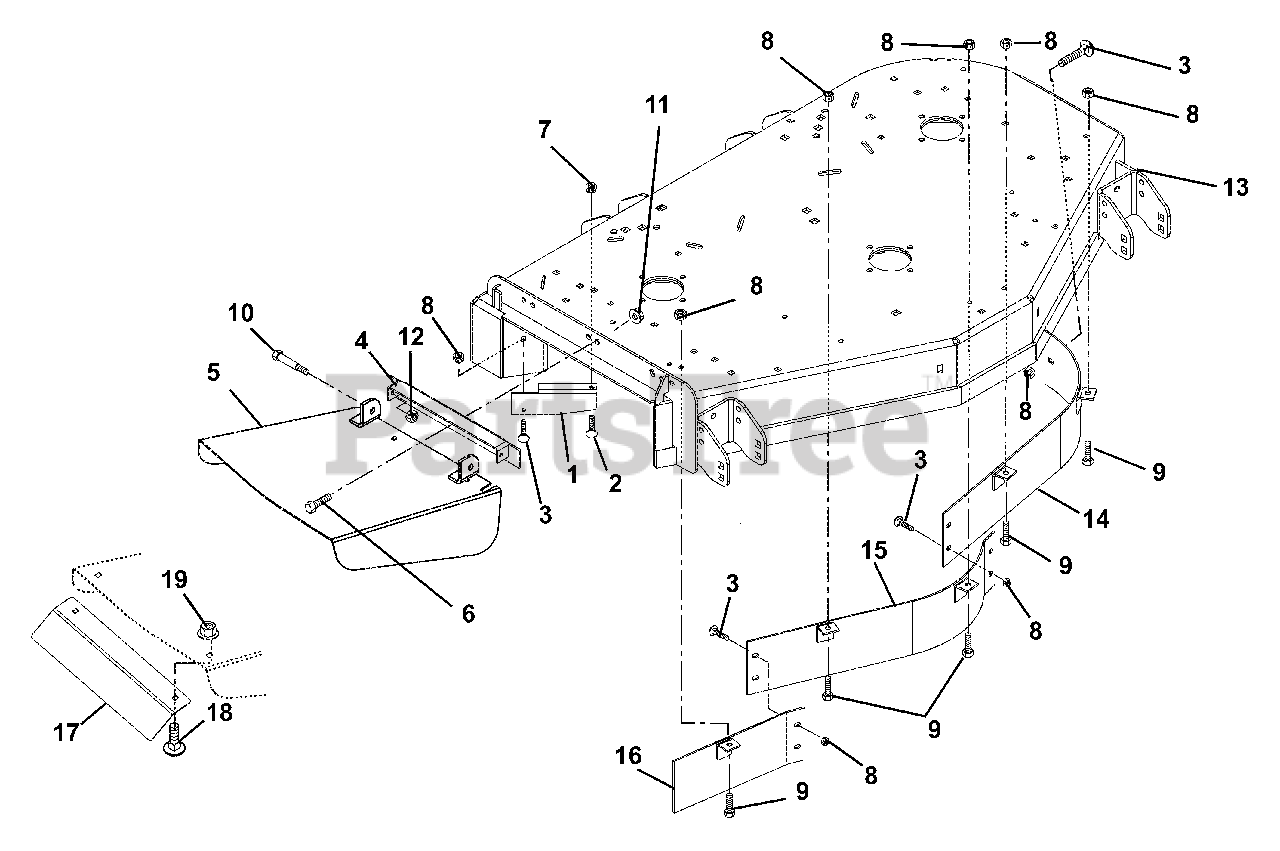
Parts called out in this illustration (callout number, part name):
1	DEFLECTOR, 60" (BLACK)
2	@BLT-RDHDSQNK .38-16X.75 G5YZ
3	@BLT-RDHDSQNK .31-18X.75 G5YZ
4	WMT, CHUTE BRKT
5	WMT, DISCHARGE CHUTE 60"
6	@BLT-HEX .38-16X1.00 GR5 YWZC
7	@NUT-LK-TOP-FLG .38-16 YWZC
8	@NUT-LK-TOP-FLG .31-18 YWZC
9	@BLT-HEX .31-18X.75 GR5 YWZC
10	BLT-SHLDR .38-16X.38 SKH
11	@NUT-SPNLK-FLG .375-16 YWZC
12	@NUT-LK-CTR .38-16 YWZC
13	60" 7 GA MOWER DECK - RED
14	BAFFLE - LEFT FRONT - 60"
15	BAFFLE - CENTER FRONT - 60"
16	BAFFLE - RIGHT FRONT - 60"
17	DEFLECTOR, CHUTE
18	@BLT-RDHDSQNK .38-16X.75 G5YZ
19	@NUT-LK-TOP-FLG .38-16 YWZC
